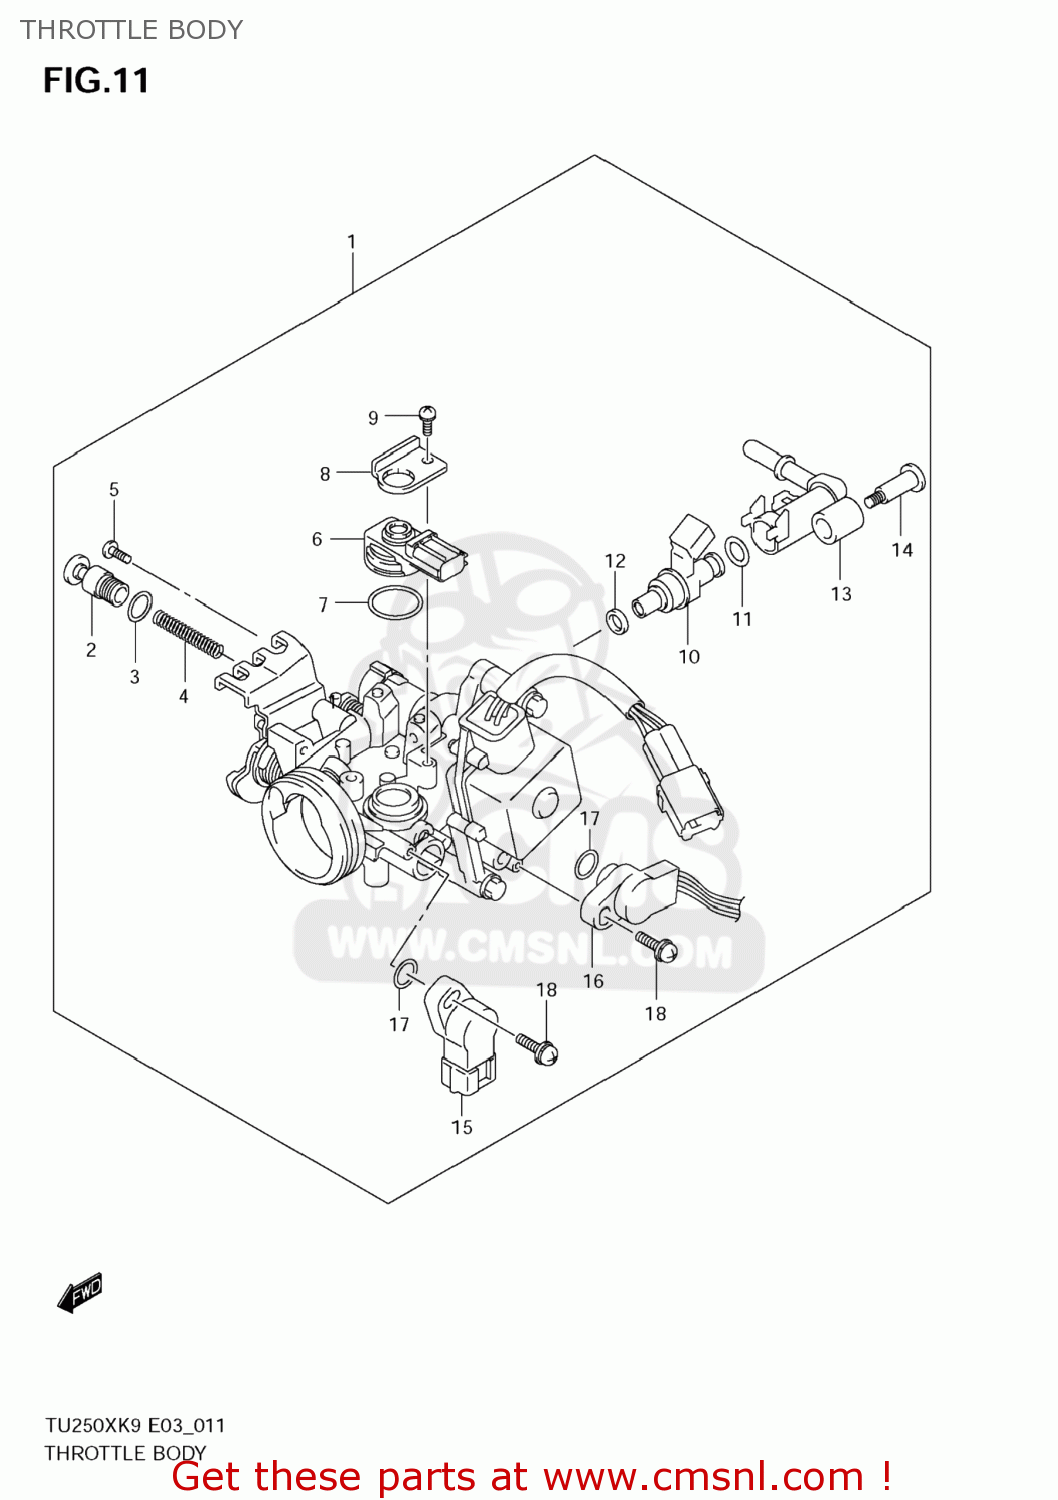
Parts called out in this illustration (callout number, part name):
1	BODY ASSY,THROTTLE
2	SCREW
3	O RING
4	SPRING
5	SCREW
6	SENSOR,MAP
7	O RING
8	PLATE,MAP SENSOR
9	SCREW
10	INJECTOR ASSY
11	O RING
12	RING,SEAL
13	PIPE,FUEL
14	SCREW
15	SENSOR,THROTTL
16	SENSOR ASSY,TH
17	O RING
18	SCREW
